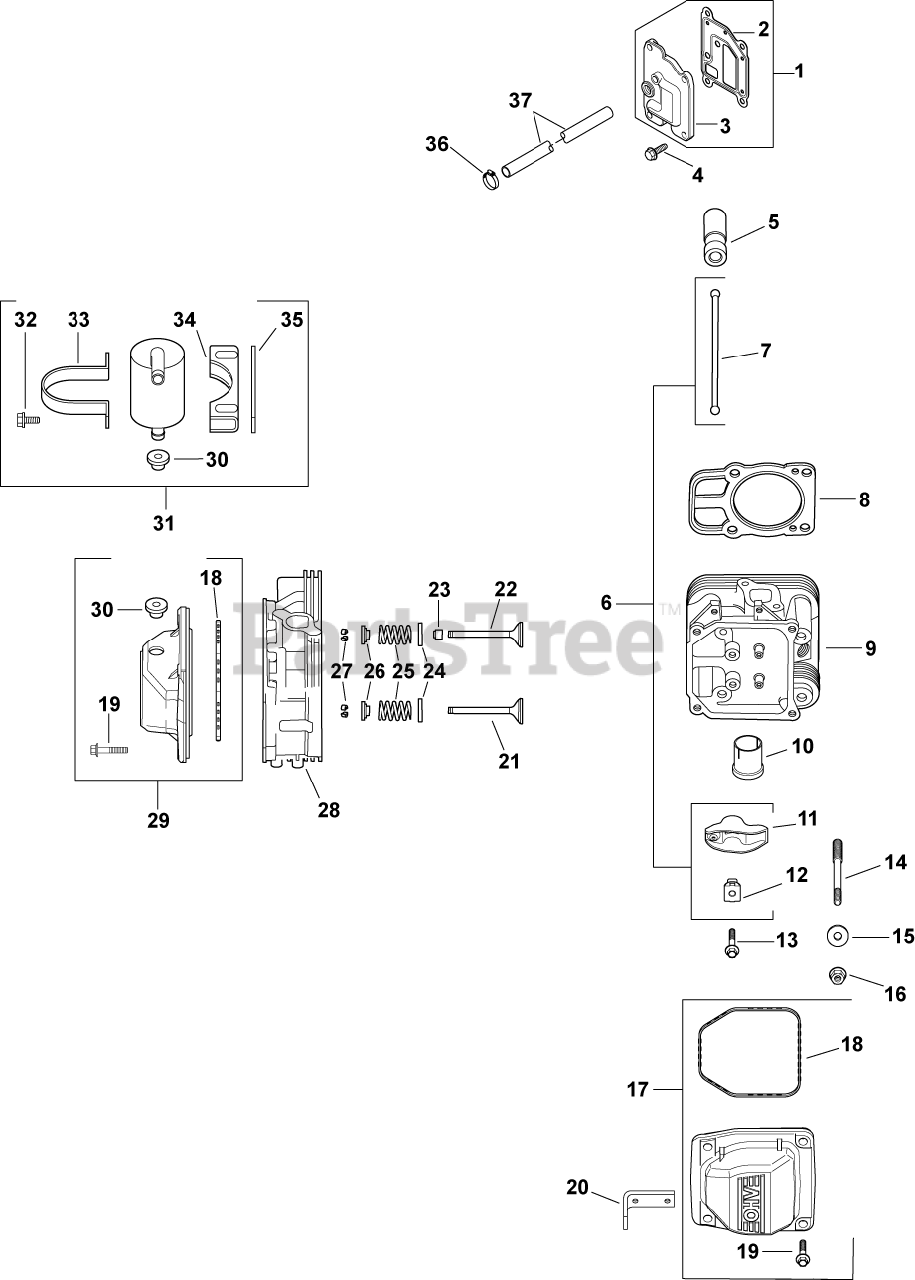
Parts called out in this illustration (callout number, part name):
1	KIT, BREATHER COVER W/GASKET
2	GASKET, BREATHER-USE 24 041 67-S
3	COVER, BREATHER -USE 24 096 125-S
4	SCREW,FLG THD FRM M6X1.0X20-(#25086396S)
5	LIFTER, HYDRAULIC VALVE-USE 25 351 10-S
6	KIT, VALVE TRAIN
7	ROD, PUSH
8	CYL HEAD GASKET KIT-USE 24 841 04-S
9	HEAD, ASSEM CYLINDER #2 -USE 24 318 116-
10	LINER, EXHAUST PORT-USE 24 605 07-S
11	PIVOT, ROCKER ARM
12	ARM, ROCKER
13	SCREW, FLG M6X1.0X34
14	STUD, M8X1.25
15	WASHER, FLAT 8.6 MM
16	NUT, FLG M8X1.25
17	KIT, VALVE COVER-PLAIN
18	O-RING (YELLOW) -USE 24 153 30-S
19	SCREW, FLG M6X1.0X30
20	STRAP, LIFTING-USE 25 445 03-S
21	VALVE, EXHAUST (STD) - USE 32 016 01-S
22	VALVE, INTAKE (STD)
23	SEAL, VALVE STEM - (#2503214S)
24	RETAINER, SPRING
25	SPRING, VALVE
26	RETAINER, VALVE SPRING - USE 25 173 28-S
27	KIT, RETAINER
28	HEAD, ASSEM CYLINDER #1 -USE 24 318 108-
29	KIT, VALVE COVER
30	GROMMET, RUBBER
31	KIT, BREATHR SEPARATR-(#24755241S)
32	SCREW,FLG THD FRM M5X0.8X16-(#25086398S)
33	STRAP, BREATHER - USE 24 755 241-S
34	BRACKET, BREATHER SEPARATOR
35	SPACER
36	CLAMP, HOSE (KM)-USE 25 237 31-S
37	HOSE, FLEXIBLE
2401602-S	VALVE, EXHAUST (.25)
2401702-S	VALVE, INTAKE (.25)
